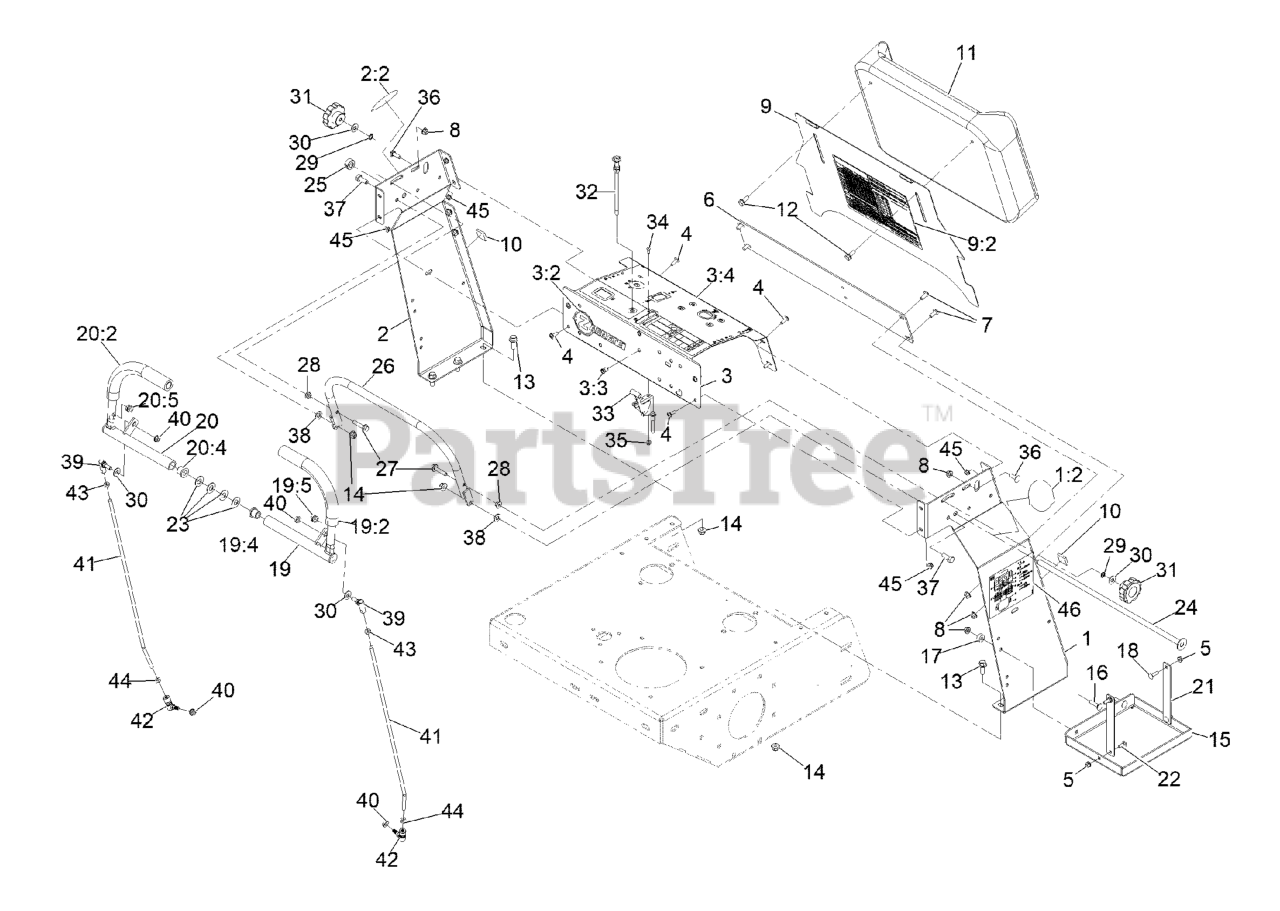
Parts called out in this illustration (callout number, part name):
1	PANEL-TOWER, LH
1:2	Decal-Z-Logo
2	PANEL-TOWER, RH
2:2	Decal-Z-Logo
3	PANEL-CONTROL
3:2	DECAL-Z-AERATE LOGO
3:3	Nut-Clinch, Hex
3:4	Decal-Control Panel
4	Screw-Hsbhf
6	PLATE-FACE
7	SCREW-PTH
8	NUT-HF, NI
9	PLATE-PAD,KNEE
9:2	Decal-Spray Chart
11	PAD-KNEE, Z-LOGO
12	SCREW-HHF
13	SCREW-HHF 3/8-16 X 1
14	NUT-HF, NI
15	TRAY-BATTERY
16	Bolt-Carriage 5/16-18 X 1 1/4
18	SCREW-CARR
19	HANDLE-CONTROL, LH ASM
19:2	GRIP-CONTROL, MOTION
19:4	Bushing,Flange,0.50 ID,0.75 OD
19:5	Grommet-Rubber
20	HANDLE-CONTROL, RH ASM
20:2	GRIP-CONTROL, MOTION
20:4	Bushing,Flange,0.50 ID,0.75 OD
20:5	Grommet-Rubber
21	Strap-Battery
22	BOLT-CARR
23	WASHER-PIVOT
24	Rod-Pivot, Joy Stick
26	Bar-Speed [red]
27	SCREW-HHF
28	Nut-Flange
29	Washer-Lock
30	FLAT WASHER, 5/16 NOM,ST
31	KNOB-FLUTED
32	CABLE-CHOKE
33	CABLE-THROTTLE
34	Screw-HSBH
35	Nut-Hex Flange
36	SCREW-CARR
37	SCREW-HH
38	WASHER-FLAT
39	Balljoint-SS
40	Nut-HHF
41	ROD-CONTROL
42	Ball Joint-Quick Disconnect, SS
43	Nut-Hex
44	Nut-Hex
45	Nut-Hex Flange
46	Decal-Service Aid
